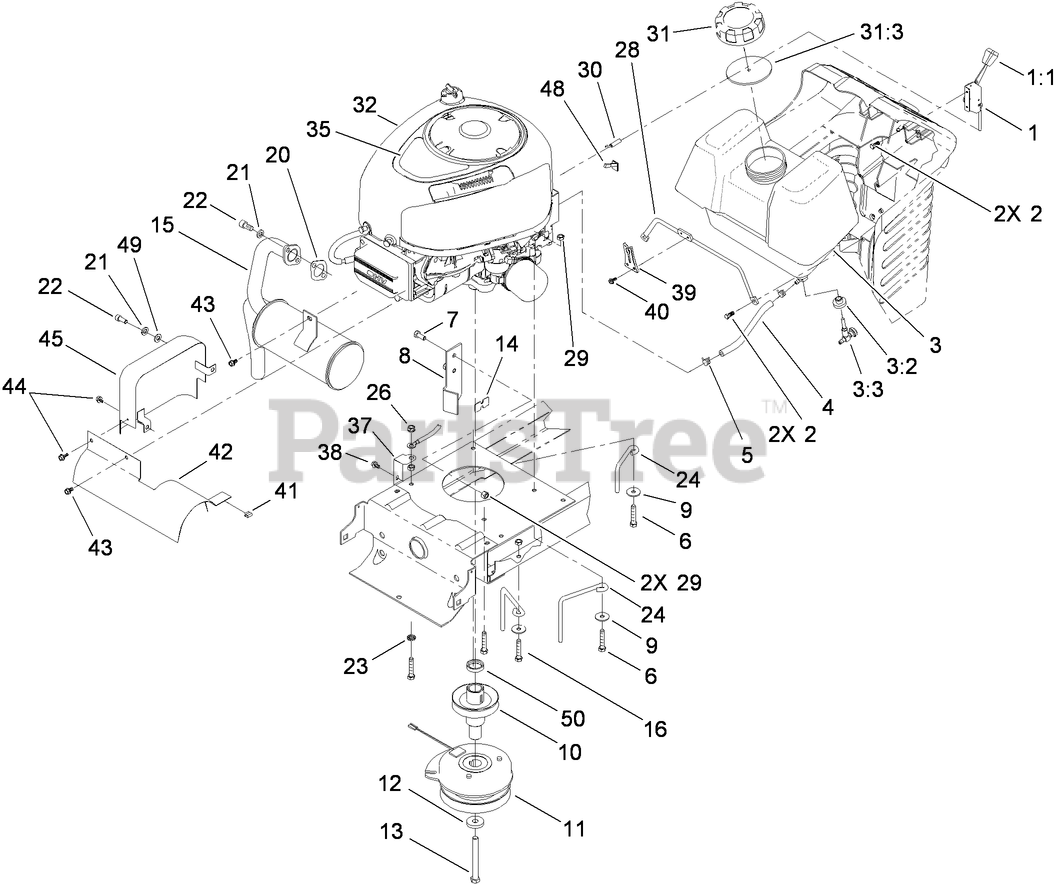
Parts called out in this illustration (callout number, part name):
1	THROTTLE CONTROL ASM
2	SCREW-SPECIAL
3	GAS TANK ASM
3:2	BUSHING
3:3	VALVE-FUEL
4	HOSE-FUEL
5	CLAMP-HOSE
6	SCREW-HH
7	SCREW-HH
8	STOP-CLUTCH
9	WASHER-PIVOT
10	PULLEY-ENGINE
11	CLUTCH-PTO, ELECTRIC
12	WASHER
13	SCREW-HH
14	BUMPER
15	MUFFLER-EXHAUST
16	SCREW-HWH, TAPTITE
20	GASKET-EXHAUST
21	WASHER-LOCK
22	SCREW-HSH
23	WASHER-LOCK
24	GUIDE-BELT, RH
26	NUT-KEPS
28	ROD-TANK, GAS
29	NUT-LOCK, NI
30	THROTTLE CABLE ASM
31	GAS CAP ASM
31:3	GASKET-CAP, GAS
35	DECAL-ENGINE
37	BRACKET-GROUND
38	SCREW-HWH
39	LATCH-HOOD
40	SCREW-HWH
41	CLIP-TINNERMAN
42	EXHAUST SHIELD ASM
43	SCREW-HWH
44	SCREW-HWHTF
45	HEAT SHIELD ASM
48	REDUCER-THROTTLE, RPM
49	WASHER-PLAIN
50	SPACER
